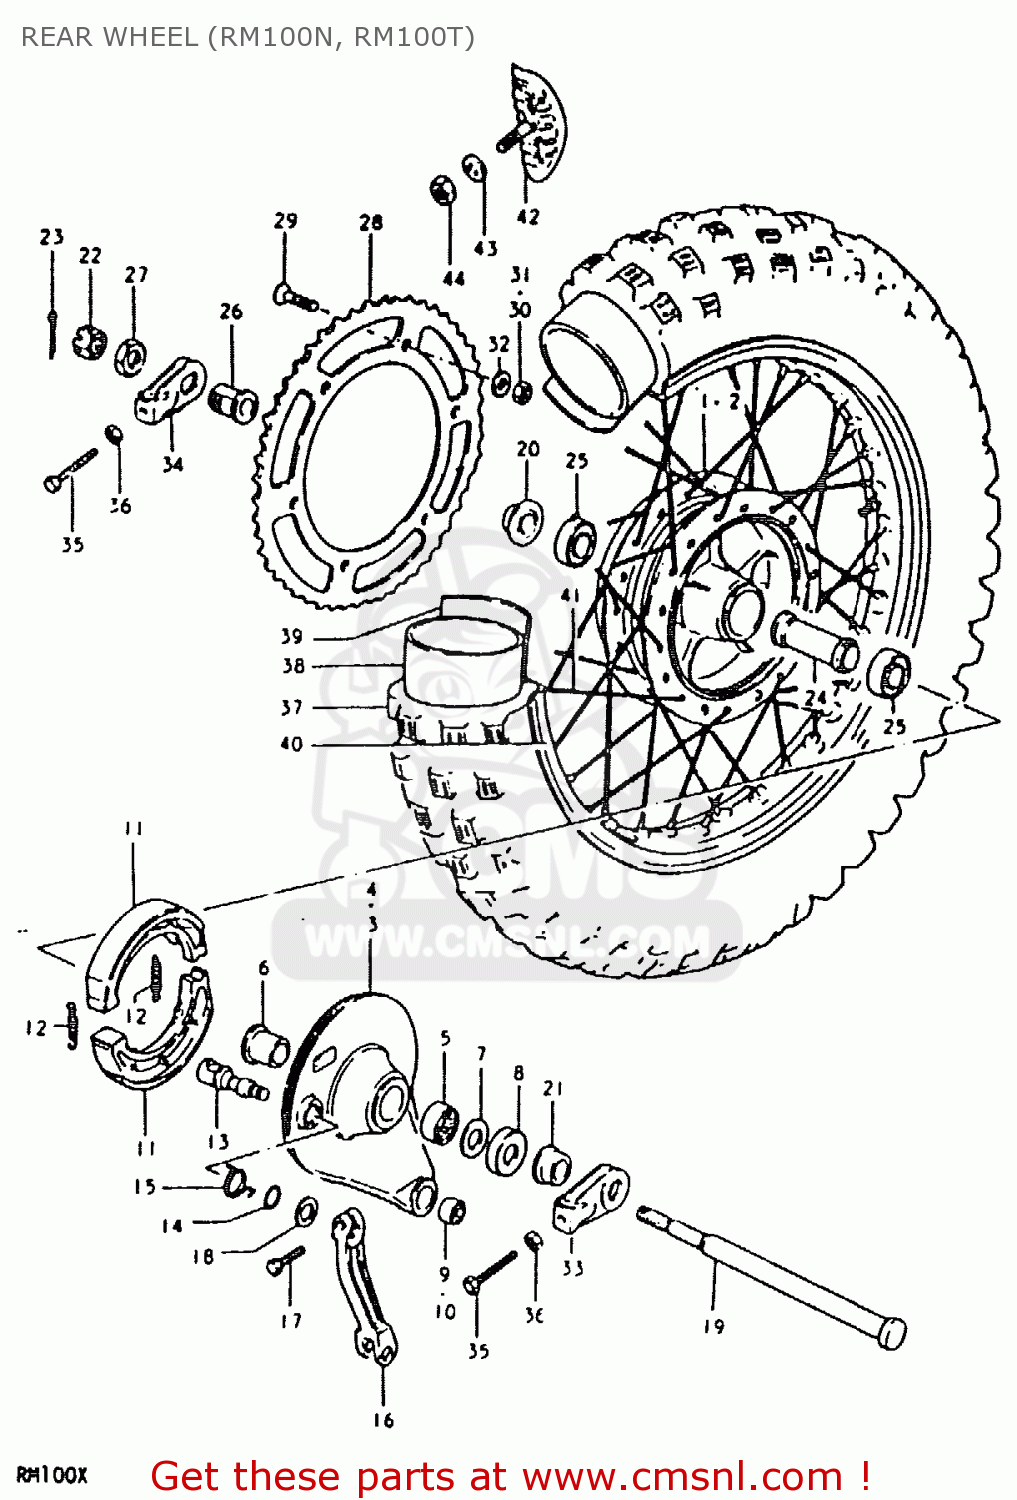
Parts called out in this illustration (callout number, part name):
1	HUB,REAR
2	HUB,REAR
3	PANEL,REAR HUB
4	PANEL SET,REAR HUB
5	BEARING(22X29X25)
6	SPACER,REAR HUB PANEL
7	WASHER
8	COVER, PANEL DUST SEAL
9	BUSH
10	SPHERICAL BEARING,TORQUE
11	SHOE,BRAKE
12	SPRING(L:34)
13	CAM,FR BRAKE
14	O RING(D:2.5,ID:11.4)
15	SPRING
16	LEVER,RR BRAKE CAM
17	BOLT
18	WASHER(12.5X20X1)
19	AXLE,REAR
20	SPACER,RR AXLE,L
21	SPACER (15.2X26X34)
22	NUT 12MM
23	COTTER PIN
24	SPACER,REAR HUB BEARING
25	BEARING
26	SPACER,CHAIN ADJUSTER,L
27	NUT
28	SPROCKET,REAR
29	SCREW(8X33.5)
30	NUT
31	NUT
32	WASHER
33	ADJUSTER,CHAIN
34	ADJUSTER,CHAIN,L
35	BOLT(8X40)
36	NUT
37	TIRE
38	TUBE ASSEMBLY,WHEEL,INNER
39	PROTECTOR,INNER TUBE
40	RIM,REAR WHEEL
41	SPOKE SET,REAR
42	STOPPER,BEAD
43	WASHER
44	NUT
